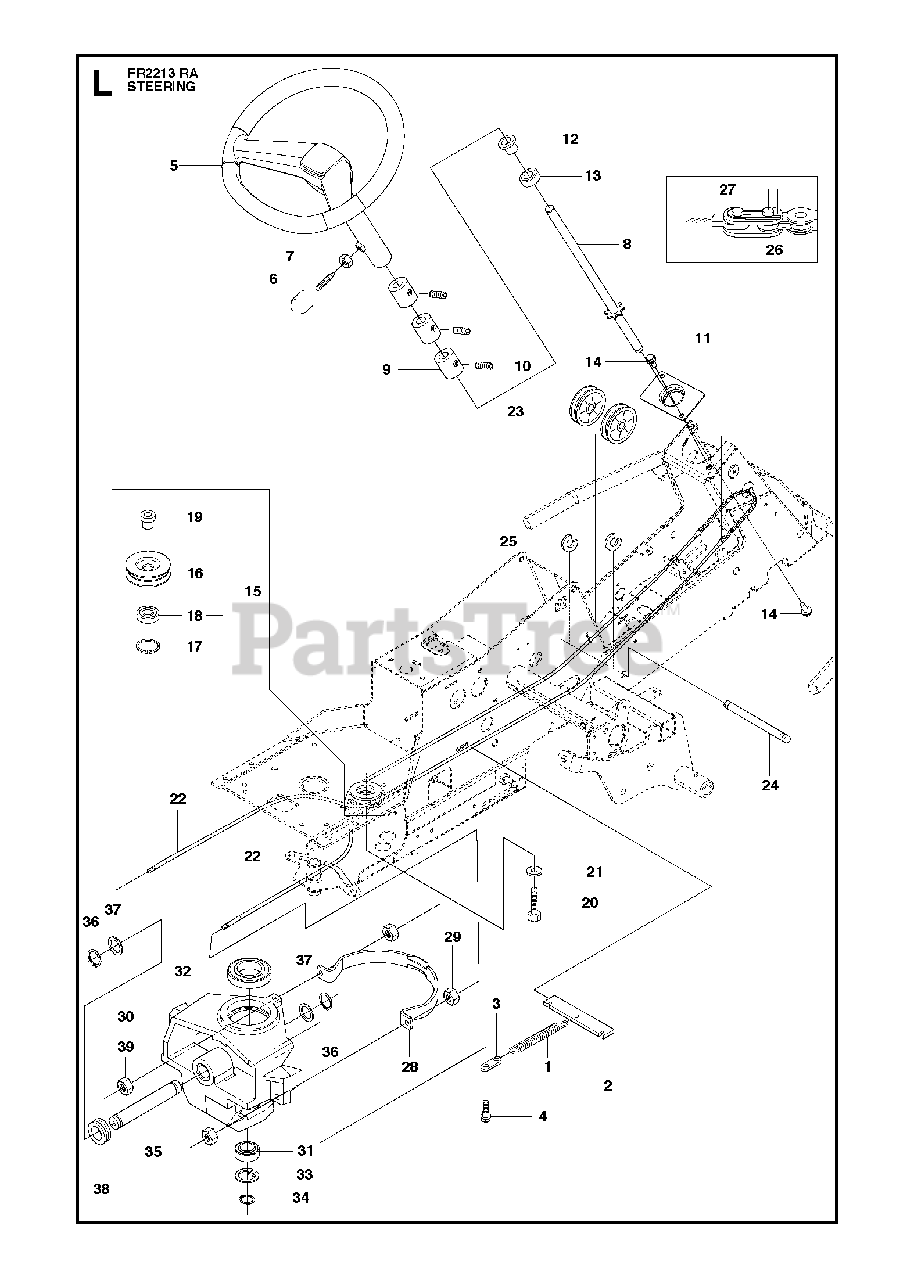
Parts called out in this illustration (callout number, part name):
2	SPRING BRACKET
3	CONNECTOR
5	STEERING WHEEL
7	NUT
8	ROD STEERING ASSY
13	BALL BEARING 6004-2RS1
16	ROLLER
17	CIRCLIP SGH 47
18	BALL-BEARING 6204-2RS
19	BUSHING
20	COLLAR SCREW
22	RP STEERING CABLE COMPLETE
25	RETAINING RING
26	STEERING CHAIN
28	WIRE GUIDE
31	BALL BEARING 6005-2RS
32	BALL BEARING 6010 2RS1
33	CIRCLIP SGH 47
34	RETAINING RING SGA 25
36	RETAINING RING SGA 25
